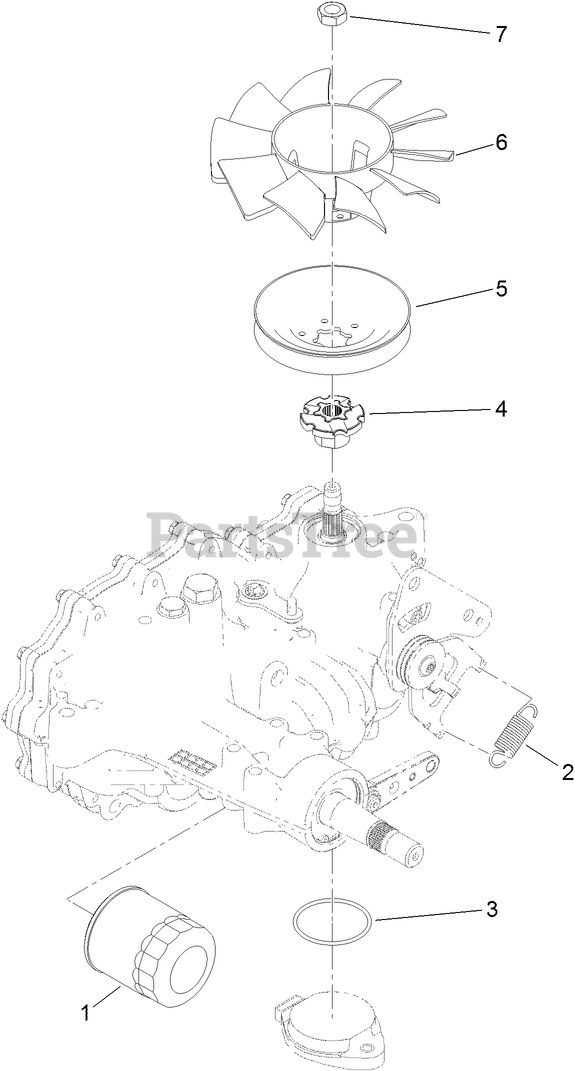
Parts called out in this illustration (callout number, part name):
1	ELEMENT-OIL FILTER, HYD
2	SPRING-EXTENSION
3	O RING-SEAL
4	HUB-PULLEY
5	PULLEY
6	FAN-7.0 INCH (10 BLADE)
7	NUT-HJ
